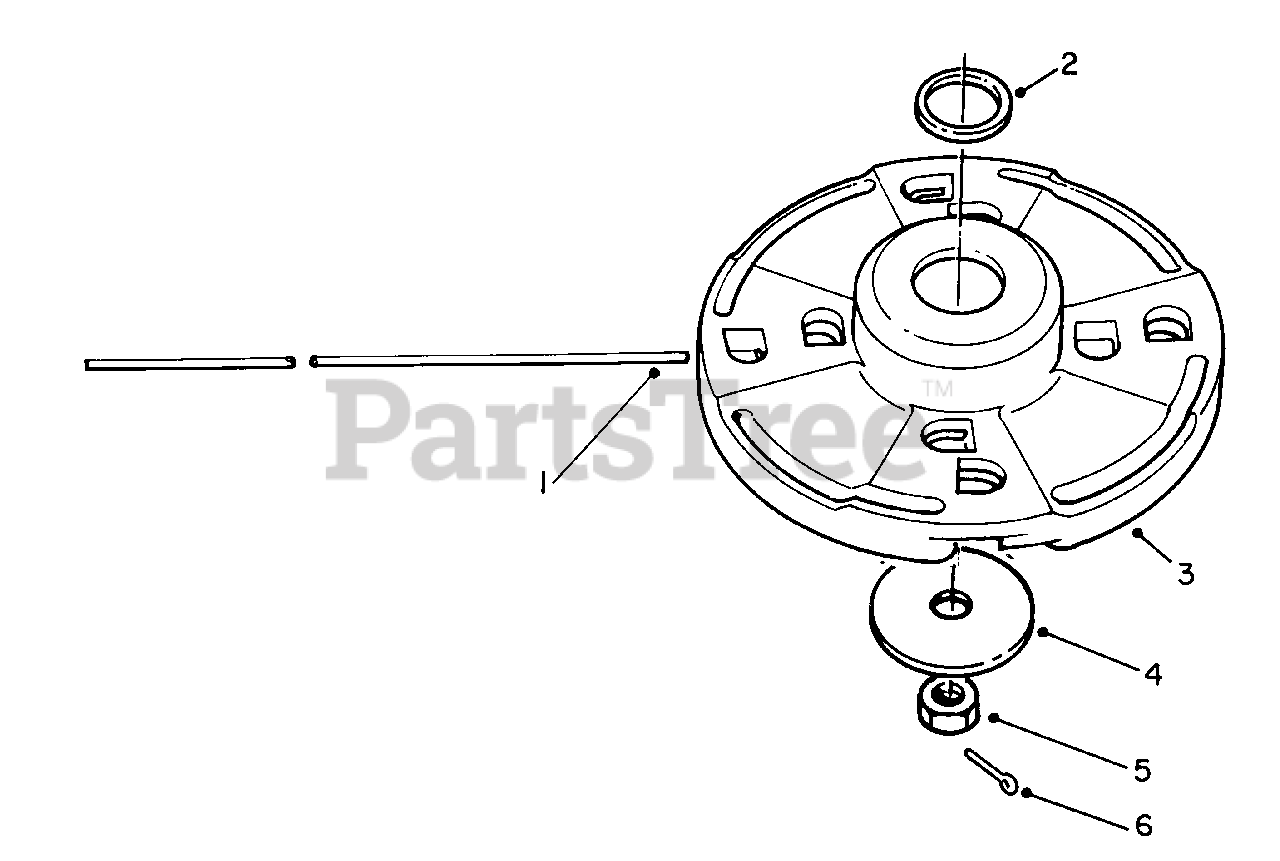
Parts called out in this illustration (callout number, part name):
1	Line-Cutting .105 Dia. (100 Pcs. Optional)
3	Head Assembly (Incl. Ref. #2)
4	Washer-Plate
5	Nut-Hex.
6	Pin-Cotter
